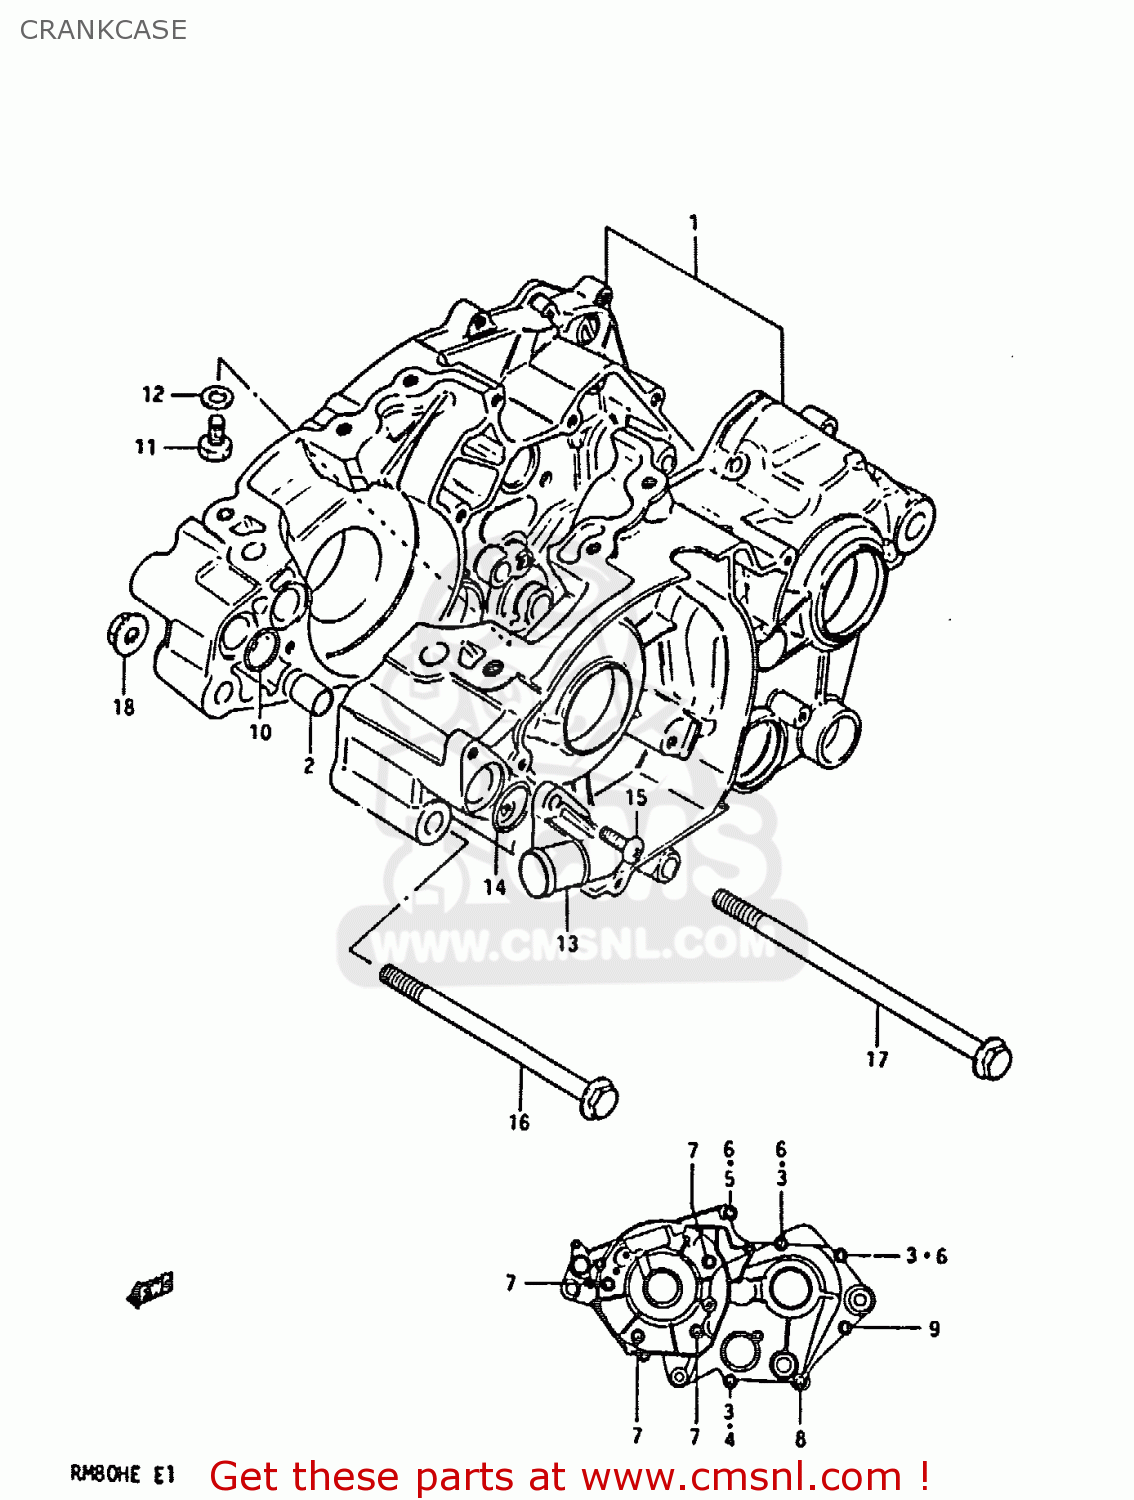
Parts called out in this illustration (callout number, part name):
1	CRANKCASE SET
2	PIN
3	SCREW
4	SCREW
5	SCREW (6X35)
6	SCREW (6X35)
7	SCREW
8	SCREW (6X45)
9	SCREW
10	O-RING,BOSS
11	BOLT
12	GASKET 8.2X14X1 (NAS)
13	CONNECTOR,WATER HOSE
14	O-RING,BOSS
15	SCREW
16	BOLT(8X95)
17	BOLT(8X125)
18	NUT
